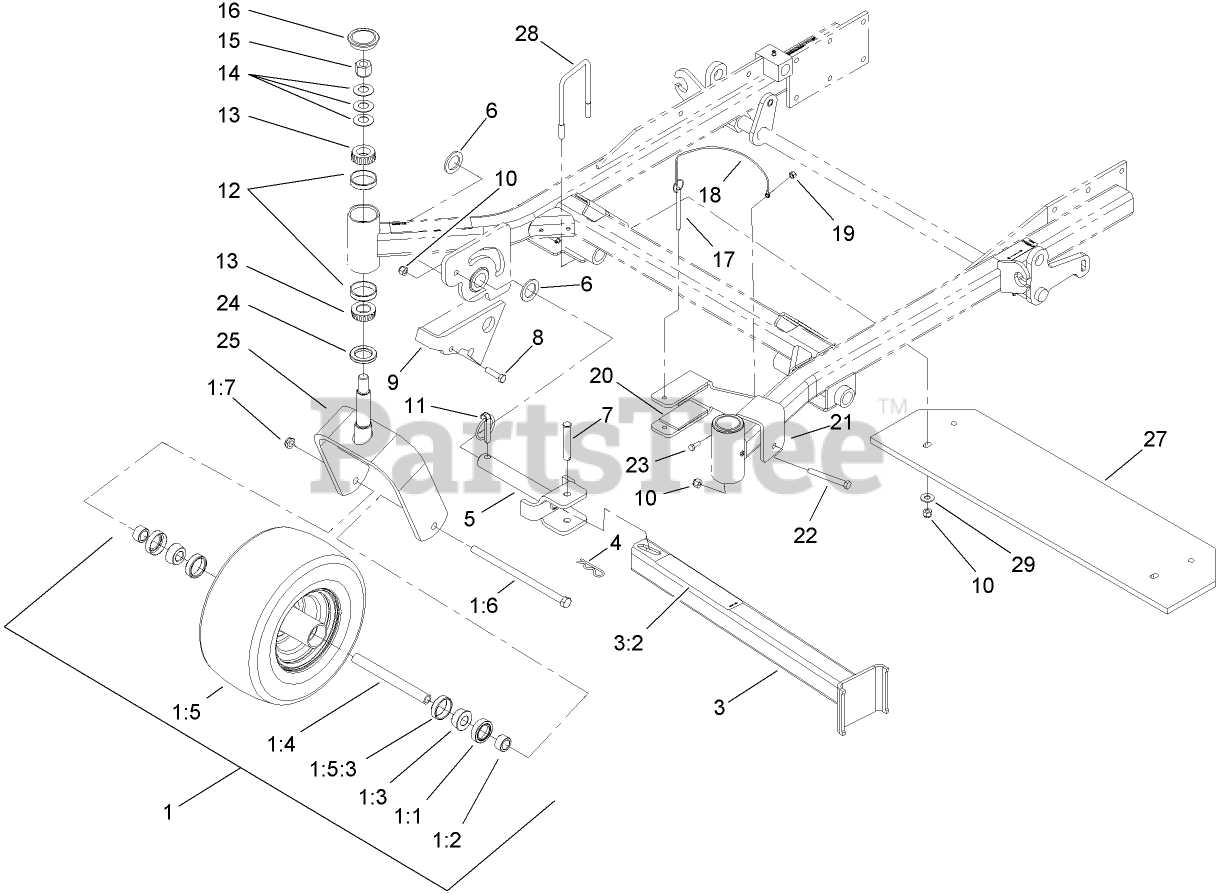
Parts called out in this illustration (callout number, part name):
1	CASTOR WHEEL ASM
1:1	SEAL-BEARING
1:2	SPACER-BEARING
1:3	BEARING-CONE, TAPER
1:4	SPACER-CASTER, FRONT
1:5	WHEEL AND TIRE ASM (SEMI-PNEUMATIC)
1:5:3	BEARING-CUP
1:6	SCREW-HH
1:7	NUT-LOCK, NI
3	Leg ASM
3:2	DECAL-Z STAND
4	PIN-HAIR
5	PIN-PIVOT
6	WASHER-THRUST
7	PIN-CLEVIS
8	SCREW-HH
9	BRACKET-LATCH
10	NUT-LOCK, NI
11	PIN-LYNCH
12	BEARING-CUP, TAPERED
13	BEARING-CONE, TAPERED
14	WASHER-BELLVILLE
15	NUT-LOCK, NI
16	CAP-GREASE
17	PIN-HITCH, COTTERLESS
18	LANYARD-NYLON
19	NUT-LOCK, NI
20	Cushion-Rubber
21	BRACKET-CRADLE
22	SCREW-HH
23	SCREW-HH
24	SEAL-GREASE
25	CASTER-FORK
27	BAR-WEIGHT
28	U-BOLT, 3IN
29	WASHER-FLAT
